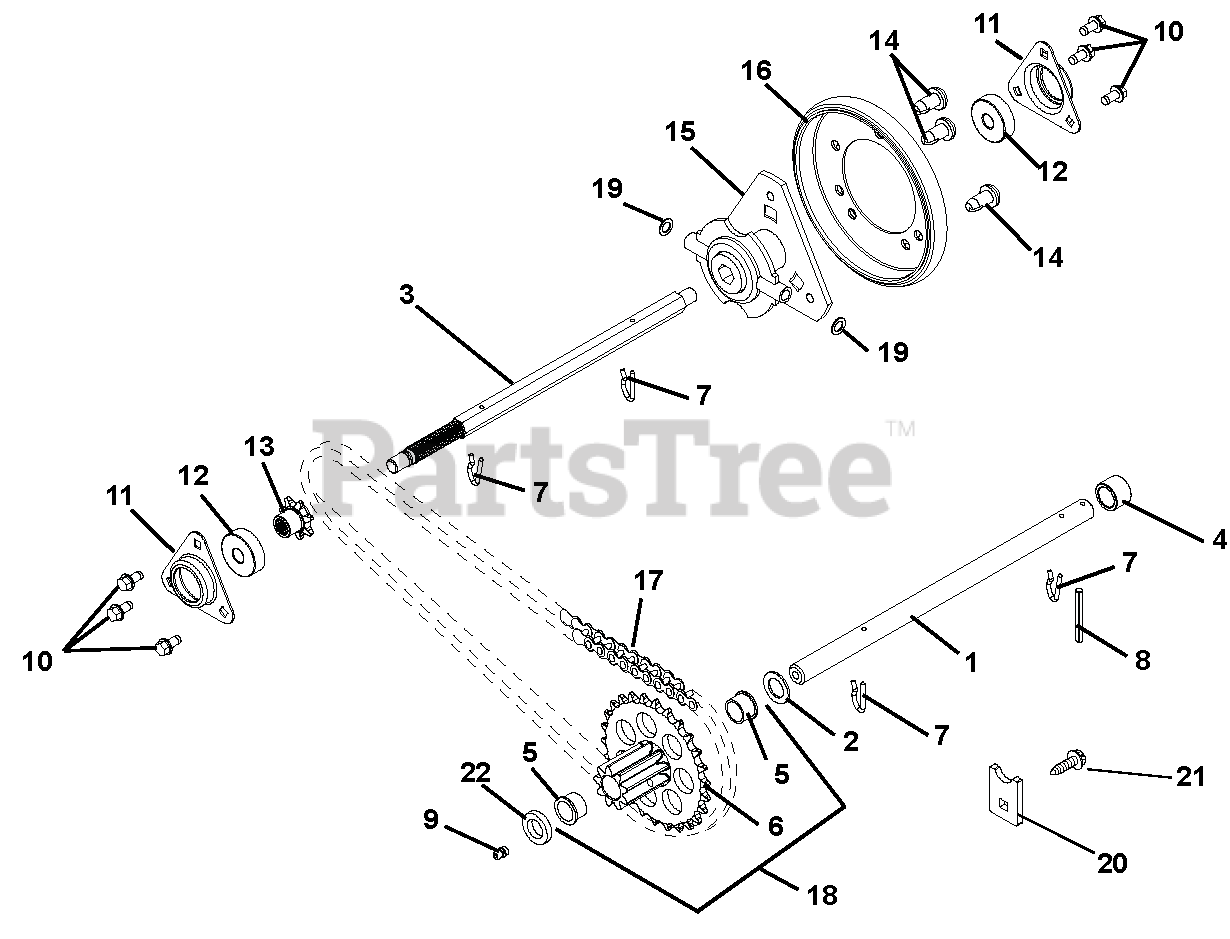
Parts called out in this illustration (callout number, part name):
1	SHAFT, PINION
2	WSHR-FL-STL .630X1.005X.062 YZ
3	SHAFT, HEX-W/SPLINE
4	SPACER, .635X.880X.611
5	BSHG-FLG .625X.750X.500X.875
6	PINION & SPROCKET
7	PIN, SPRING CLIP
8	PIN-ROLL .125X1.00
9	ZERK,FITTING .25X.125 DRIVE IN
10	@SCR-TAP .25-20X.50 HWH TR YWZ
11	FLANGE, BEARING
12	BRG-BALL .437X1.375X.437
13	SPROCKET, PINION 7T W/SPLINE
14	SCR-TAP SERRDHDTX .31-18X.50BP
15	CARRIER, DRIVE DISK
16	FRICTION, DISC
17	CHAIN - #41, 32 PITCHES
18	PINION & SPROCKET W/BUSHINGS
19	WSHR-FL-STL .505X1.00X.062YWZC
20	TAB, ANTI ROTATION
21	@SCR-TAP .25-20X.50 HWH TR YWZ
22	BSHG-SLV, .635X.880X.305
